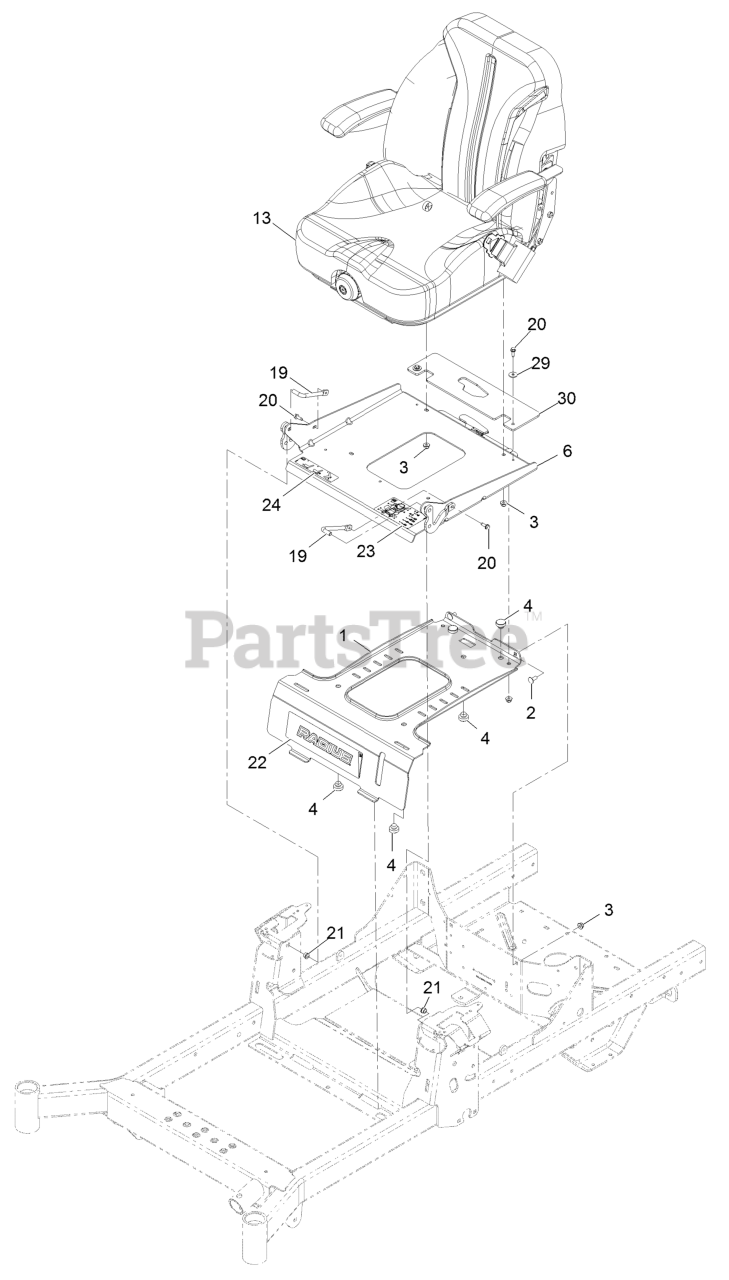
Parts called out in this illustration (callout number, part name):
1	PLATE-RETAINER, TANK
2	SCREW-CARR
3	NUT-HF, NI
4	BUMPER-SEAT
6	SEAT PAN AND LATCH ASM
13	ASM-SUSP SEAT
19	PIN-PIVOT, SEAT
20	SCREW-HWH, THREAD ROLL
21	BUSHING-FLANGED
22	DECAL-RADIUS LOGO
23	DECAL-AID, SERVICE
24	DECAL-LATCH, SEAT
30	GUARD-SEAT, RUBBER
